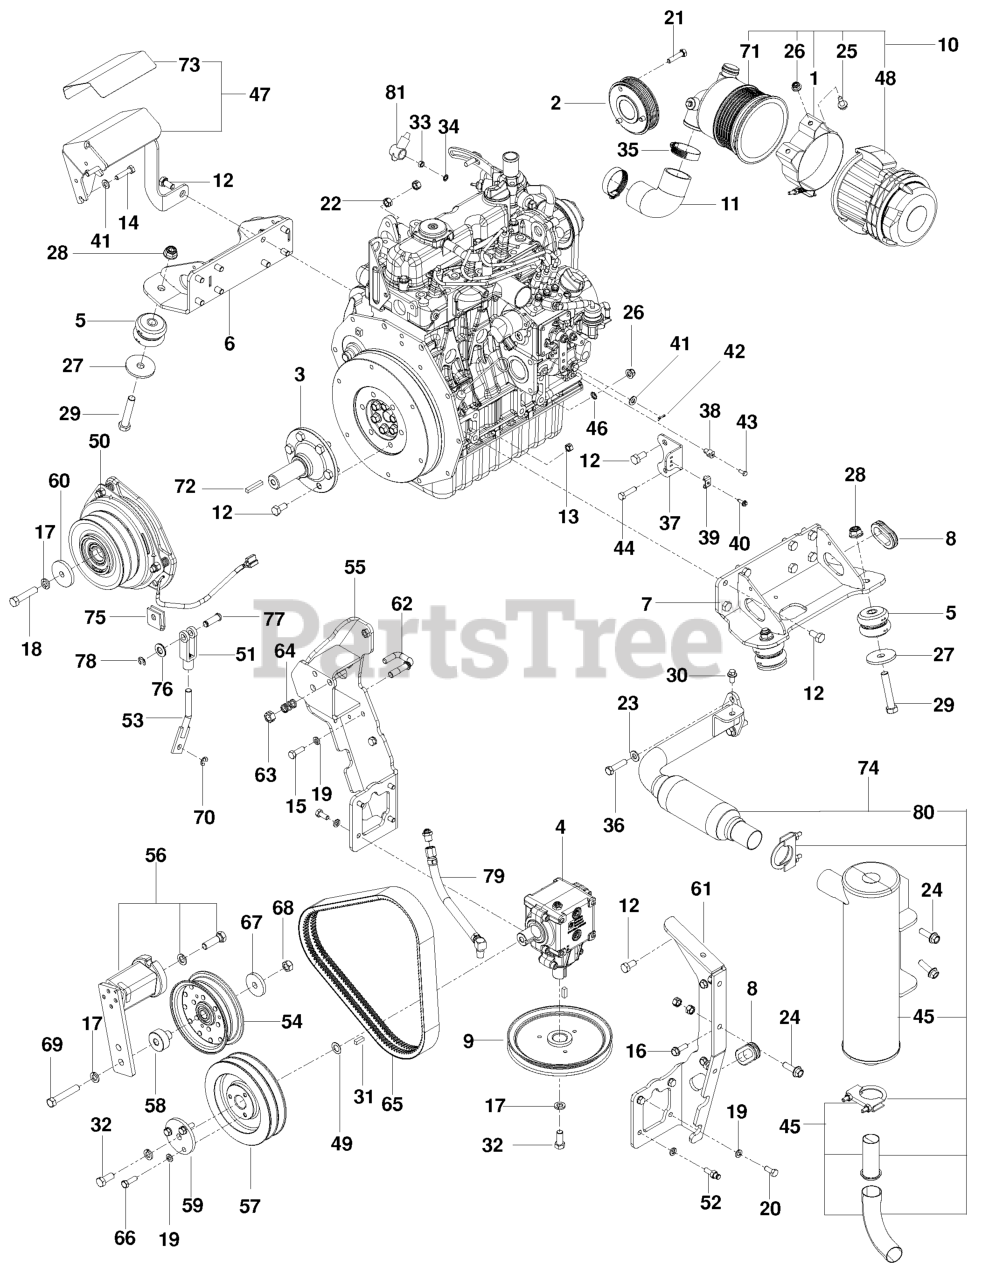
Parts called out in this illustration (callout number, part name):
1	MOUNTING BRACKET
2	PULLEY, CRANK
3	SHAFT, PILOT
4	GEAR BOX, 90 DEGREE
5	ISOLATOR, ENGINE
6	MOUNT, MOTOR, LT - BLK
7	MOUNT, MOTOR, RT - BLK
9	PULLEY, DRIVE, DECK
10	AIR FILTER ASSY - NON-TURBO
11	HOSE, AIR INTAKE
12	HCS M10-1.25 X 20 GR 8.8 ZD
13	NUT 5/16C CENTERLOCK
14	HTB M8-1.125 X 25MM
15	M8X1.25X25 HHB GR8.8
16	5/16-18X1 TAP SCREW
17	WASHER 7/16 LOCK
18	HCS 7/16-20 X 2 G8 ZN
19	WASHER.LOCK.HVY.HLCL.SPR.5/16
20	SCREW 5/16C X 1 HEX CAP
21	HCS MB 1.25 X 35 GR 8.8 ZD
22	NUT 3/8C CENTERBLOCK
23	WASHER 3/8 SAE FLAT
24	HHFS 3/8-16 X 1.25 GD 5
25	BOLT 5/16-18 X 3/4
26	5/16-18 NYLOC FLANGE NUT
27	WASHER, HEAVY
28	NUT, 1/2-13 HEX FLG NYLOC ZD
29	HCS 1/2C X 2 3/4
30	SCREW M8X1.25X16 HHB GR 8.8
31	KEY 1/4 SQ X 3/4
32	SCREW 7/16-20 X 1 HHB GR5
33	NUT M6 X 1.0 HEX
34	WASHER 1/4 INT TOOTH
36	HCS 3/8C X 1 1/2
37	BRACKET, THROTTLE
38	SWIVEL, THROTTLE
39	CLAMP, CABLE
40	SCREW #10 X 1/2 SELF TAPPING
41	FLAT WASHER 5/16 SAE
42	COTTER PIN 3/32 X 1/2
43	HCS #10-24 X 1/2
44	HCS 5/16C X 1 1/4
45	KIT.SPARK.ARRESTER
46	WASHER 5/16 EXT STAR
47	SHIELD, HEAT
48	PRECLEANER ASM
49	WASHER .515 X .874 X .031
50	CLUTCH, OGURA, DIESEL
51	YOKE, CLEVIS
52	PIN, PIVOT
53	LINKAGE, ANTI-ROTATION
54	IDLER PULLEY
55	MOUNT, GEAR BOX, BLK
56	TENSIONER, LOVEJOY, SE27
57	PULLEY, GEAR BOX
58	MOUNT, IDLER
59	PLATE, PULLEY
60	BLADE WASHER
61	MOUNT, GEAR BOX, BLK
62	PIN, DETENT
63	NUT 7/16C CENTERLOCK
64	SPRING, COMPRESSION
65	BELT, CLUTCH
66	HCS 5/16C X 1
67	SPINDLE WASHER
68	NUT, 7/16-20 HEX NYLOC ZC
69	BOLT 7/16F X 2 1/2
70	E RING 3/8"
71	BODY - 90 DEG
72	KEY 1/4 SQ X 1-1/2
73	SHIELD, HEAT BARRIER
74	MUFFLER.DIESEL.KUBOTA
75	SPACER, RUBBER
76	WASH 1/2 X 1 SPRG STL & NEOP
77	PIN, 7/16 CLEVIS
78	RING, E, 7/16
79	HOSE, VENT
80	PIPE, MANIFOLD, DIESEL
81	TERMINAL COVER-SM
